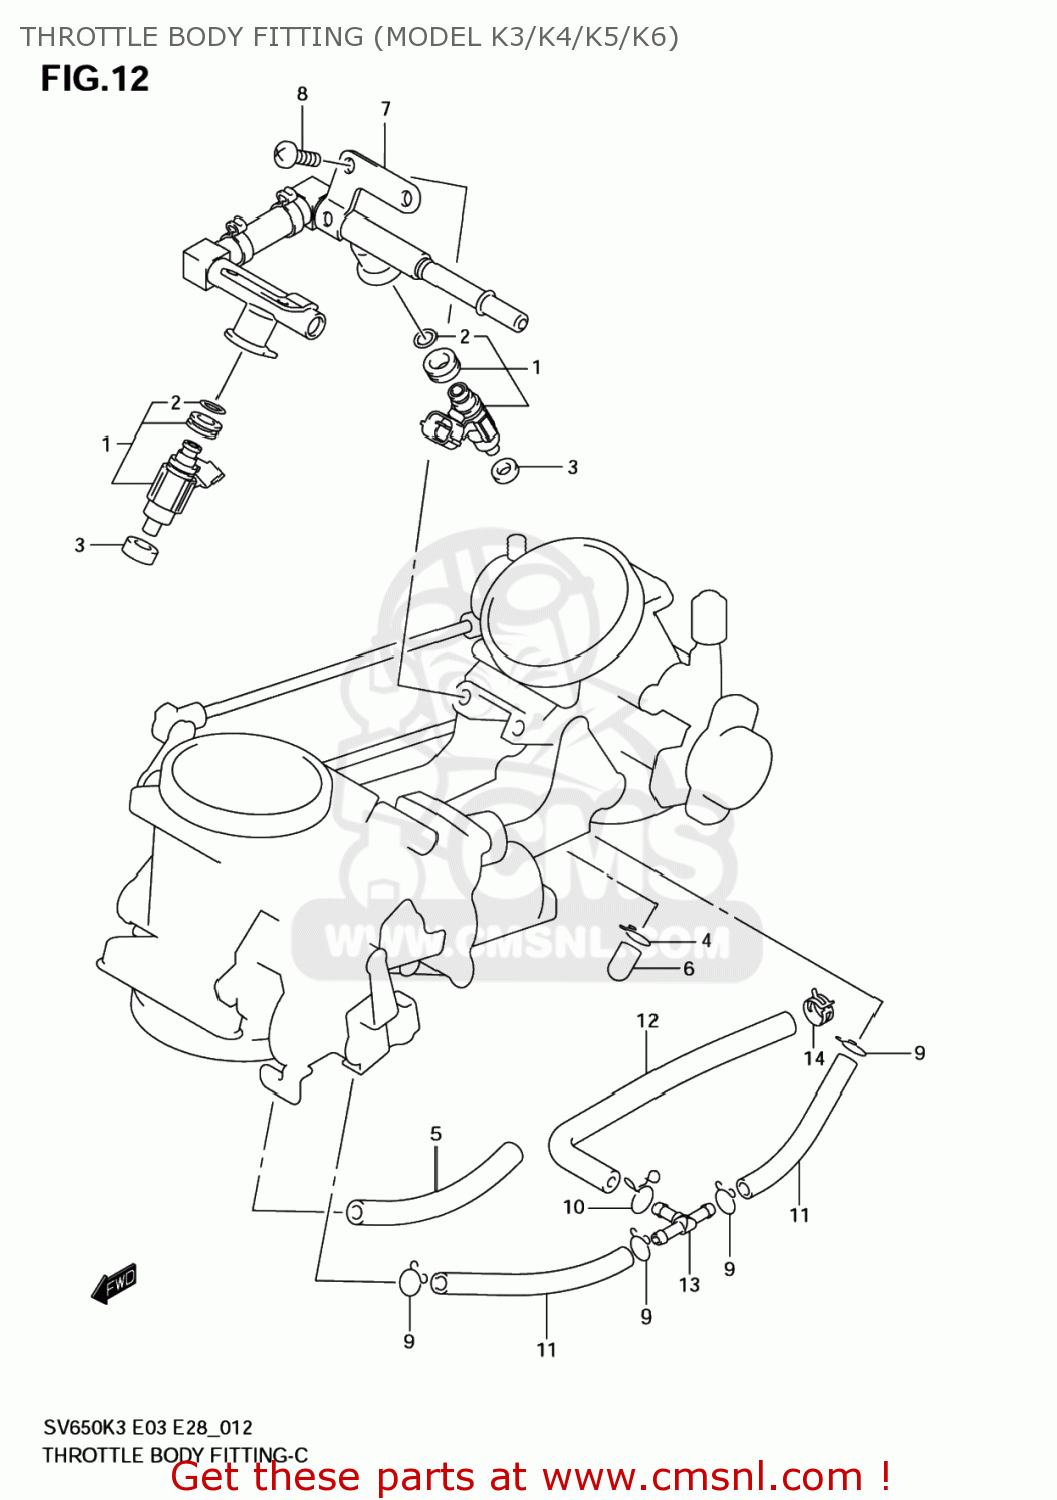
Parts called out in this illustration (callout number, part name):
1	INJECTOR ASSY
2	O RING
3	CUSHION,FUEL INJECTOR
4	CLIP
5	HOSE(3.2X7.4X225)
6	CAP
7	DELIVERRY PIPE
8	SCREW
9	CLIP
10	CLIP
11	HOSE(3.2X7.4X225)
12	HOSE
13	NIPPLE
14	CLIP
